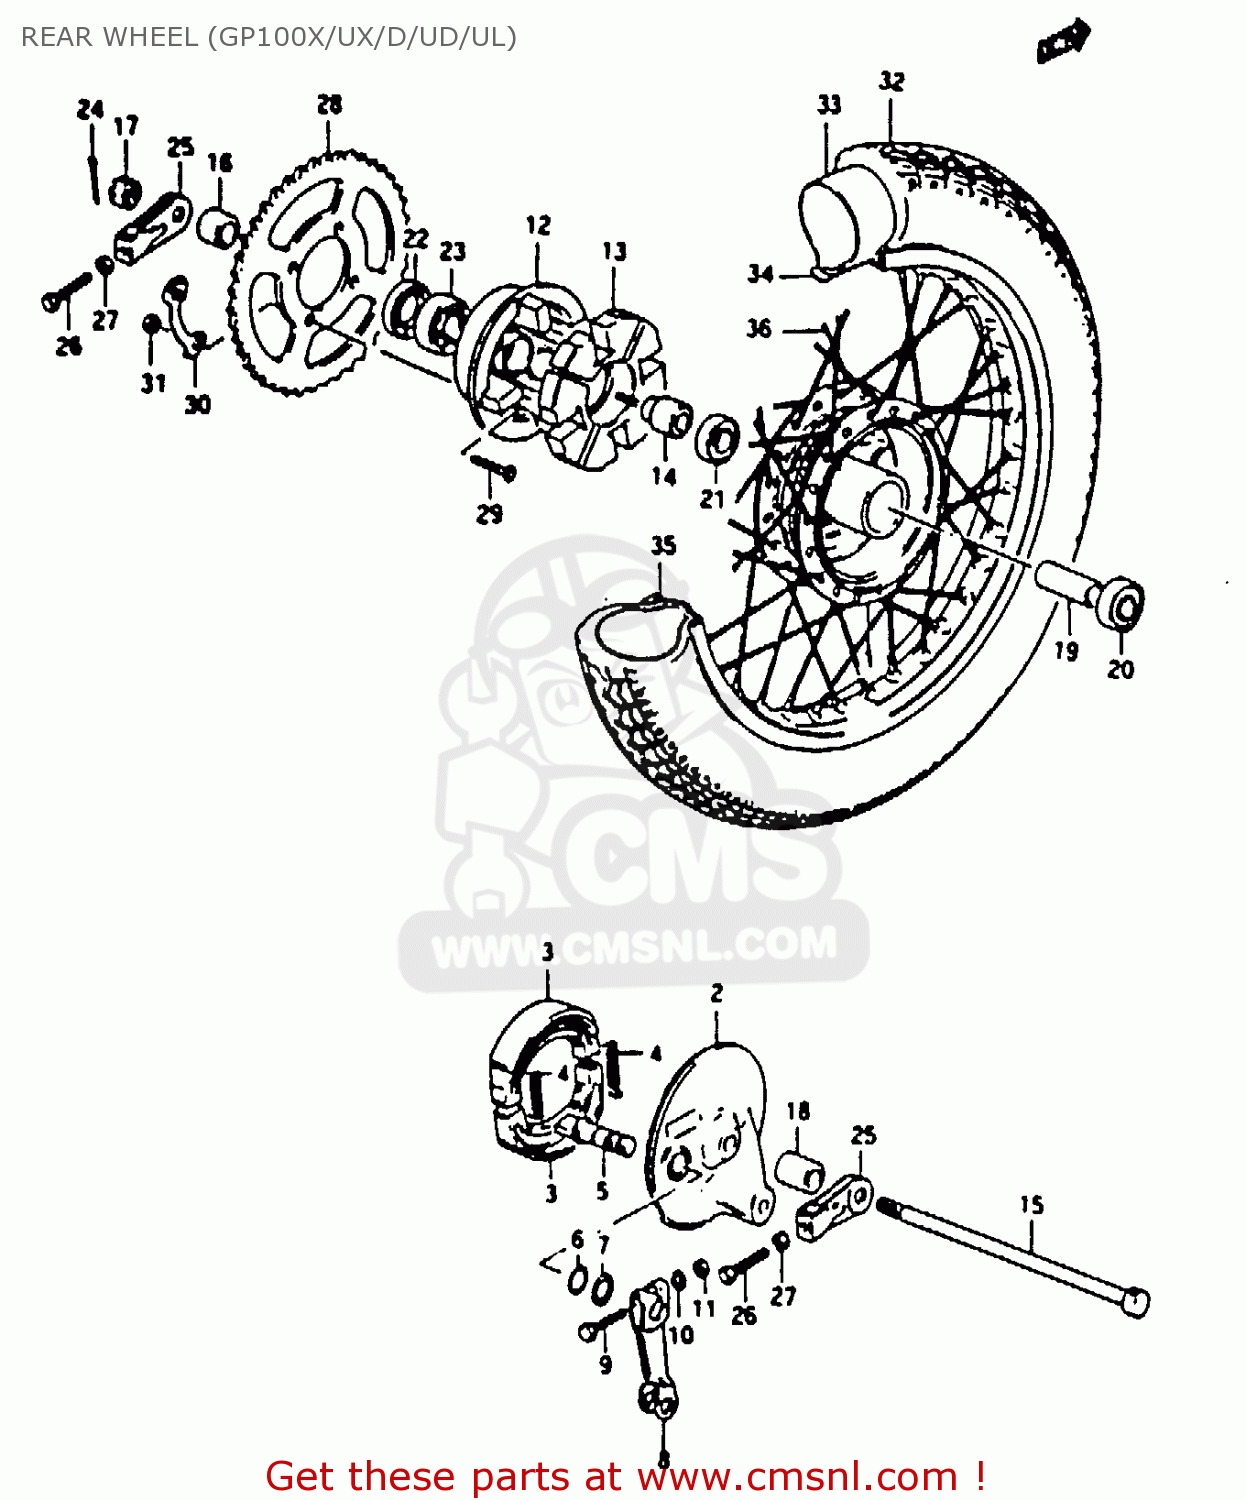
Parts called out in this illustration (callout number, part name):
1	HUB, WHEEL
2	PANEL,RR BRAKE ANCHOR
3	SHOE,BRAKE
4	SPRING(L:34)
5	CAM,FRONT BRAKE
6	O-RING (D:2.4 ID:13.8)
7	WASHER (14.5X22X1.6)
8	LEVER,RR BRAKE CAM
9	BOLT(6X33)
10	WASHER
11	NUT
12	DRUM,RR SPROCKET MOUNTING
13	CUSHION,REAR DRUM
14	RETAINER,RR SPROCKET DRUM
15	AXLE, REAR
16	SPACER 12X25X2
17	NUT 12MM
18	SPACER(12.2X22X39)
19	SPACER (12.6X19X58)
20	BEARING
21	BEARING
22	SEAL OIL(25X40X6)
23	BEARING(17X40X12)
24	COTTER PIN
25	ADJUSTER, CHAIN
26	BOLT
27	NUT
28	SPROCKET, REAR (NT:42)
29	BOLT(8X33.5)
30	WASHER
31	NUT
32	TIRE,RR(2.75-18 42P)
33	TUBE,INNER
34	PROTECTOR,WHEEL,INNER
35	RIM,WHEEL(1.40X18)
36	SPOKE SET,RR
